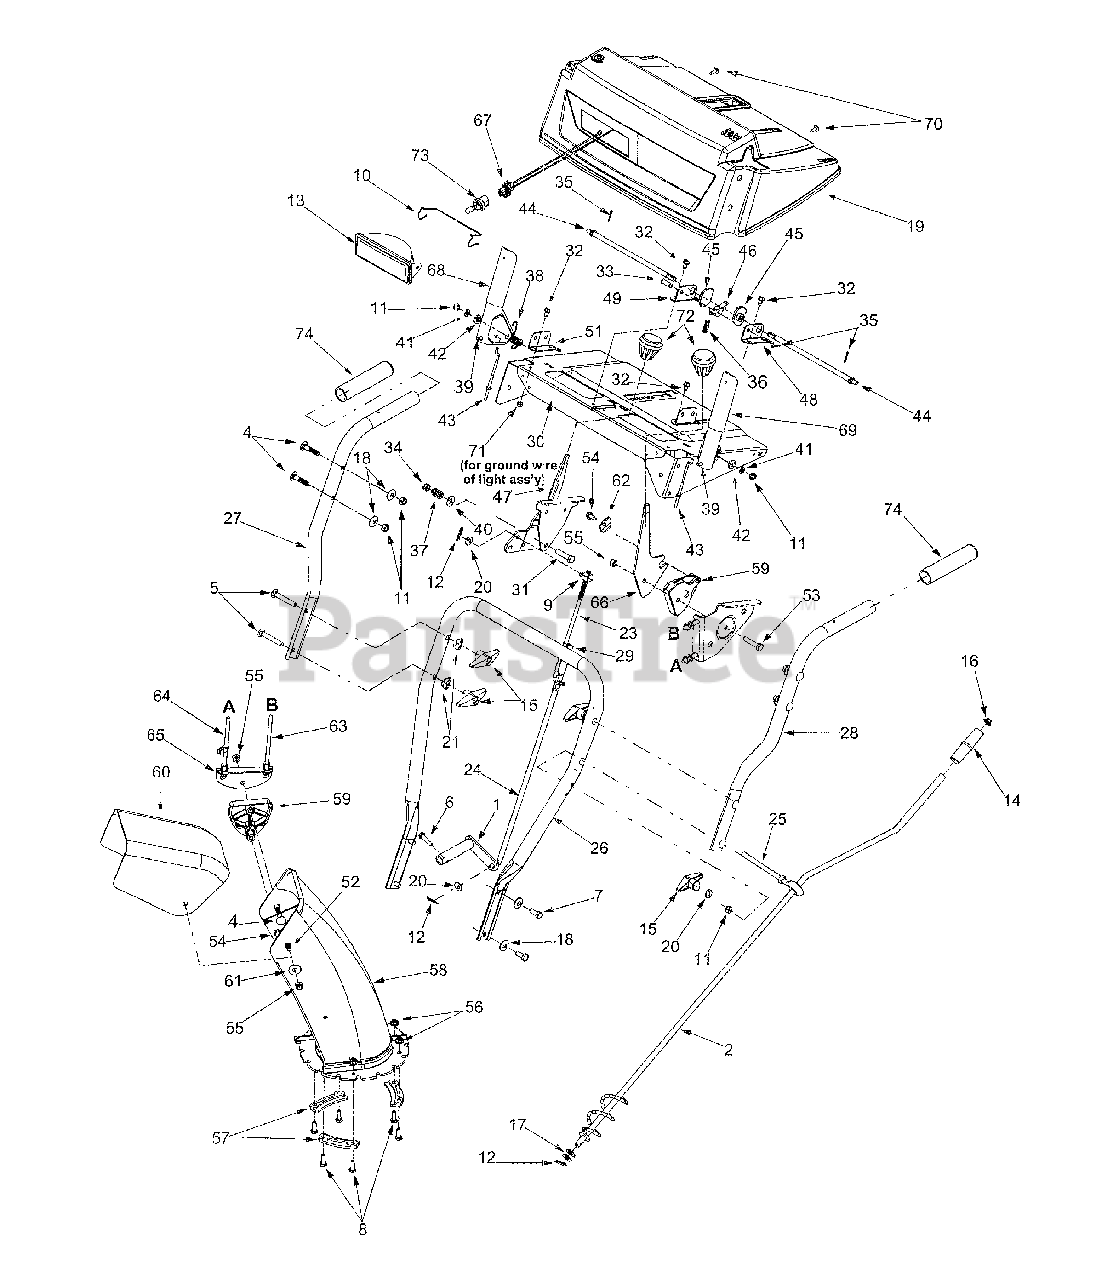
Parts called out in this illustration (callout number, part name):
1	Shift Arm Assembly
2	Chute Crank Ass'y
4	Carriage Bolt, 5/16-18 x 1.5
5	Carriage Bolt, 5/16-18 x 2.25
6	Self Tapping Screw, 1/4-20 x 1
7	Hex Cap Screw, 5/16-18 x .75
8	Hex Cap Screw, 1/4-20 x .75
9	Ferrule, 5/16-18 x .2.12
10	Headlamp Retainer
11	Hex Nut, 5/16-18
12	Internal Cotter Pin
13	Lens Assembly / Lamp Housing
14	Chute Crank Knob
15	Wing Knob, 5/16-18
16	Push Cap, 3/8
17	Flat Washer, .375 x .738 x .063
18	Bell Washer, .34 x .872
19	Handle Panel
20	Flat Washer, .344 x .688 x .065
21	Saddle Washer, .32 x .93
22	Plastic Bushing
23	Upper Shift Rod
24	Lower Shift Rod
25	Eyebolt
25	Eyebolt Grommet
31	Hex Cap Screw, 3/8-24 x 1.5
32	Self Tapping Screw, 1/4-20 x.5
33	Clevis Pin
34	Jam Nut, 3/8-24
35	Cotter Pin, 3/32 x .75
36	Compression Spring, .36 x 1.0
37	Comp. Spring, .39 x.6 x .88
38	Torsion Spring, .44 x .8
39	Rubber Bumper
40	Bell Washer, .401 x .87 x .063
41	Lock Washer, 5/16
42	Special Washer, .35 x .72 x. 13
43	Cable "Z" Fitting
44	Cam Rod
45	Cam Handle Lock
46	Handle Lock Pawl
47	Shift Handle
48	LH Handle Support Bracket
49	RH Handle Support Bracket
51	RH Handle Support Bracket
52	Carriage Bolt, 5/16-18 x .75
53	Hex Cap Screw, 516-18 x 1.5
54	Screw, 1/4-14 x .625
55	Hex Lock Nut, 5/16-18
56	Hex Flange Lock Nut, 1/4-20
57	Lower Chute Flange Keeper
58	Lower Chute
59	Chute Tilt Cable Guide
60	Upper Chute
61	Washer, 5/16
62	Special Washer, .28 x 1.2 x .06
63	Chute Deflector Control Cable
64	Chute Deflector Cable w/ Clip
66	Chute Tilt Handle
67	Halogen Light Harness
68	RH Engagement Handle Ass'y
69	LH Engagement Handle Ass'y
70	Special Screw, #10-16 x .625
71	Hex Sems Nut, 1/4-20
72	Plastic Knob
73	Halogen Lamp, 12-volt, 27 Watt
74	Handle Grip
